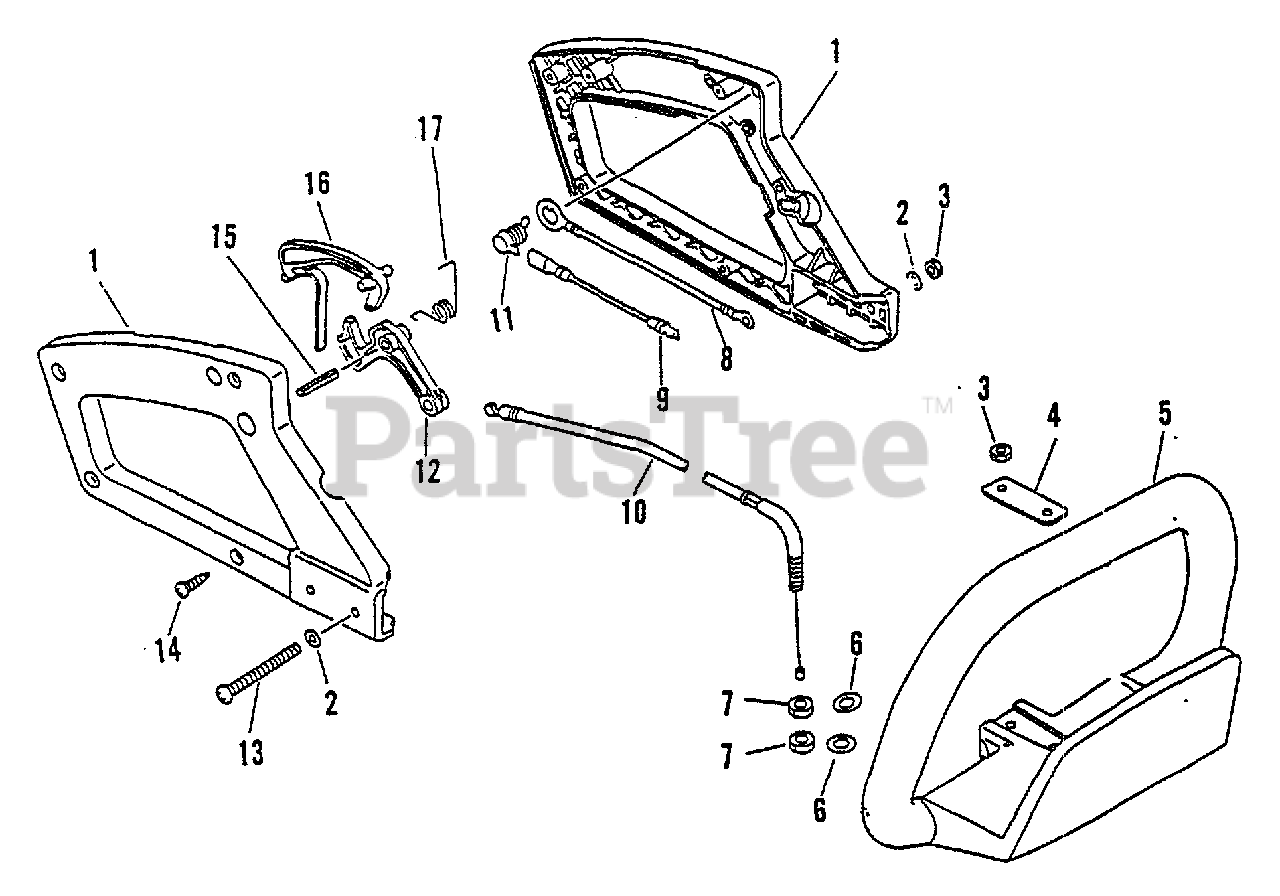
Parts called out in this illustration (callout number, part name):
1	HANDLE ASSY - REAR
2	WASHER - 5
3	LOCKNUT - 5
5	HANDLE - FRONT
6	WASHER - 6
8	LEAD - GROUND
9	LEAD - GROUND
10	CABLE, THROTTLE
11	IGNITION SWITCH ASSY
12	TRIGGER, THROTTLE
13	SCREW - 5X55
14	SCREW - 4X16
15	PIN - SPRING -- 5X25
16	LOCKOUT, THROTTLE
17	SPRING, TRIGGER
